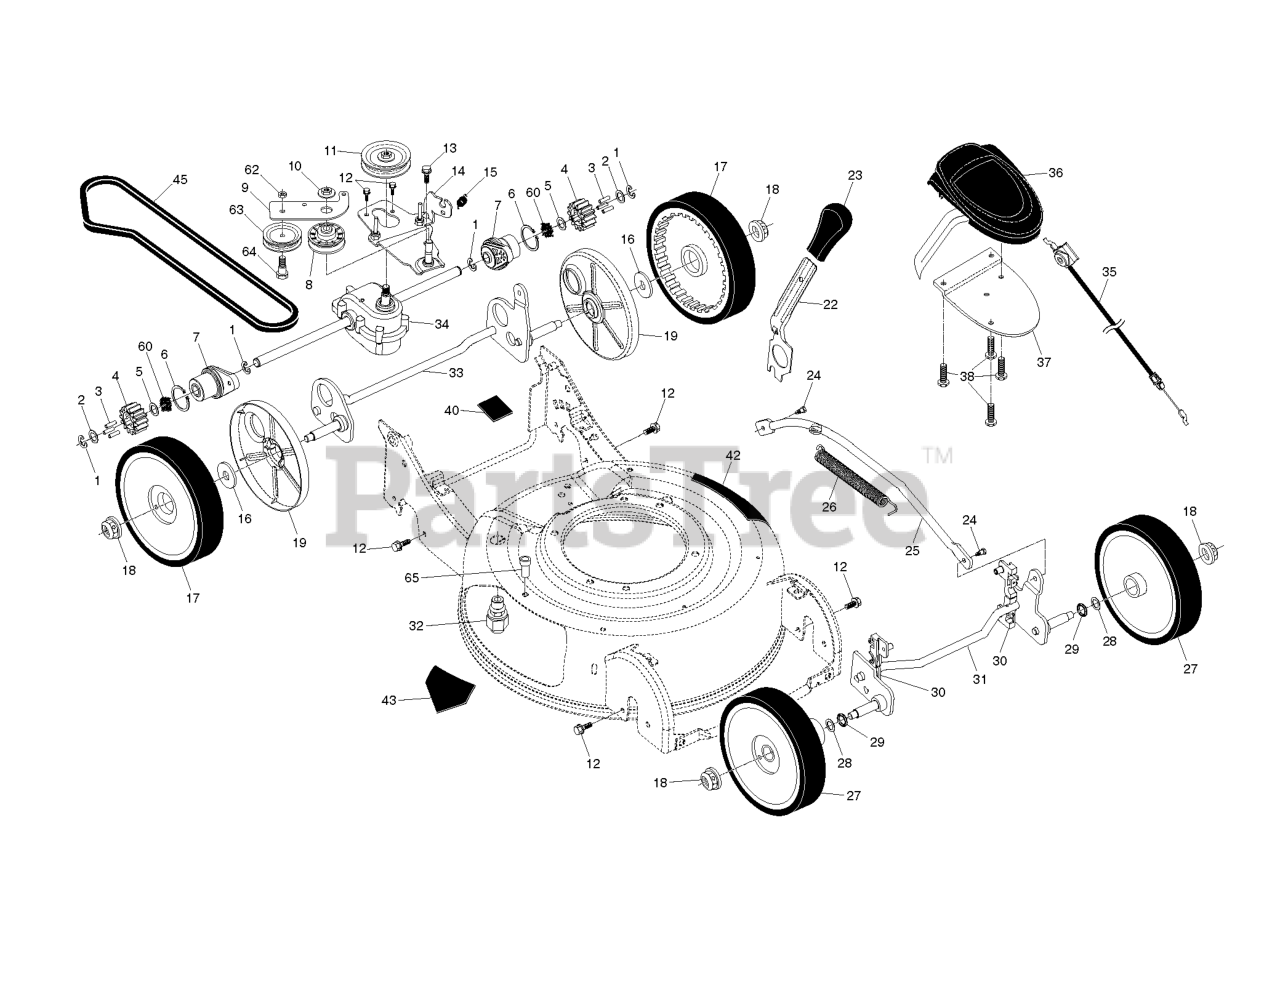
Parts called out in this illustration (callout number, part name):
1	E-RING 7/16 RE
2	THRUST WASHER
3	PAWL.DRIVE.ETCHED
4	PINION.DRIVE.WALK
6	RETAINING RING (2 2)(3 2)
7	BEARING.ASM
8	PULLEY.IDLER.V-BELT
9	ARM.IDLER.BZP
10	NUT.HEX.FLANGE.3/8-16.LOCKNUT
11	PULLEY.1.PIECE
13	SCREW 14-20 X 5/8
15	SPRING.RETURN
16	WASHER FLUT
17	WHEEL.8X1.75.H3SPK.RAD3.GY.BU3
18	NUT.HEX.FLANGE.3/8-16.LO(3 2)
19	COVER.DUST.WHEEL
24	SHOULDER BOLT SEMI GIMLET PT.
25	ROD.LIFT.BZP
26	SPRING EXTENSION
27	WHEEL & TIRES ASSY, FRONT
28	WASHER.FLAT.1/2
29	O-RING..070X.487.NEOPRENE
30	BUSHING.FRONT.TORQUE.SHAFT
37	BRACKET.DRIVE.CONTROL.MOUNT.BL
38	SCREW, PHILLIPS HEAD 10 X 5/8
43	DECAL.INTERNATIONL.CUTFINGER
62	NUT.CENTERLOCK.5/16-
63	IDLER PULLEY
64	SHOULDER BOLT
